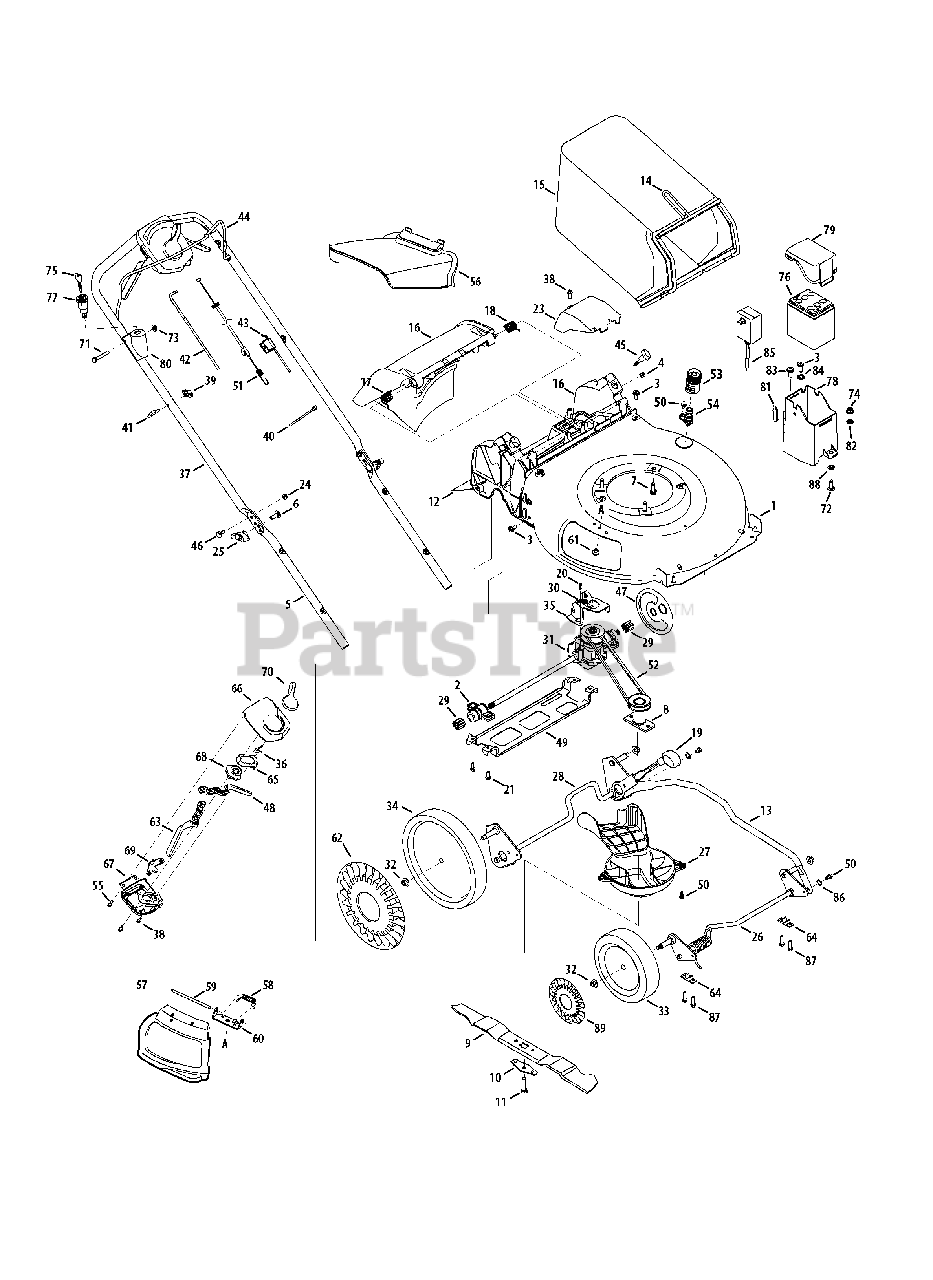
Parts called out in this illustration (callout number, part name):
1	21" Deck Ass’y
2	Bearing Assembly
3	Hex Hd. Cap Scr. 5/16-14 x .75
4	Sq. Nut 1/4-20
5	Lower Handle
6	Carriage Bolt 5/16-18
7	Hex Wash HD Tap Scr 3/8-16 x .88
8	Blade Adapter
9	21" Mulching Blade
10	Blade Bell Support
11	Hex Bolt 3/8-24 x 1.5" Lg. (Gr 8)
12	Trailing Shield 4.54 x 17.37
13	Cross Bracket
14	Catcher Frame
15	Grasscatcher Bag
16	Rear Baffle Ass’y (Incl. door)
17	RH Torsion Spring
18	LH Torsion Spring
19	Knob (Black)
20	Sems TT Scr. 1/4-20 x .50
21	Screw 1/4-15 x 1.25
23	Transmission Cover
24	Flanged Lock Nut 1/4-20 Gr. F Nylon
25	Wing Knob-Black
26	Front Axle Ass’y
27	Engine Baffle
28	Rear Axle Ass’y
29	Spur Gear 9T
30	Extension Spring 2.405
31	Transmission Ass’y
32	Flange Locknut 3/8-16 Gr. F Nylon
33	Front Wheel
34	Rear Wheel
35	Transmission Bracket
36	Spring
37	Upper Handle - Black
38	Screw, 1/4-15 x .750
39	Knob 1/4-20
40	Cable Tie
41	Rope Guide Bolt
42	Drive Cable
43	Control Cable (Honda)
44	Blade Control
45	Knob 1/4-20 x 1.73 Black
46	Shoulder Screw .375 x .126 x 1/4-20
47	Dust Cover
48	Control Lever LH
49	Rear Support Bracket
50	Shoulder Scr. 1/4-20 x .50
51	Speed Adjustment Cable
52	V Belt
53	Water Nozzle Adapter
54	Deck Water Nozzle
55	Shoulder Screw 1/4-15 x .970
56	Chute Deflector
57	Mulching Plug Ass’y (Incl. ref. no. 58-60)
58	Torsion Spring
59	Hinge Pin
60	Chute Deflector Bracket
61	Screw 1/4-20 x .50
62	Hub Cap
63	Control Lever RH
64	Bushing .505 Dia. x .62
65	Cable Adjust Plate
66	Upper Housing
67	Lower Housing
68	Speed Adjust Actuator
69	Hub Cap 8"
70	Speed Select Lever
71	Hex. Hd. Cap Scr. 1/4-20 x 1.75 Gr. 5
72	Carriage Bolt 5/16-18 x 1.0
73	Hi -Lo Scr. 5/16-14 x .75
74	Hex Ins. L-Nut 5/16-18
76	Battery
77	Key Switch
78	Battery Housing
79	Battery Housing - Top
80	Switch Housing
81	Seal, Lid
82	Cupped Washer .340 x .872 x .060
83	Shoulder Screw 5/16-14 x .972
84	Spacer .340 x .460 x .246
85	Charger
86	Wave Washer
87	Screw 1/4-15
88	Speed Nut
89	Hub Cap 8"
